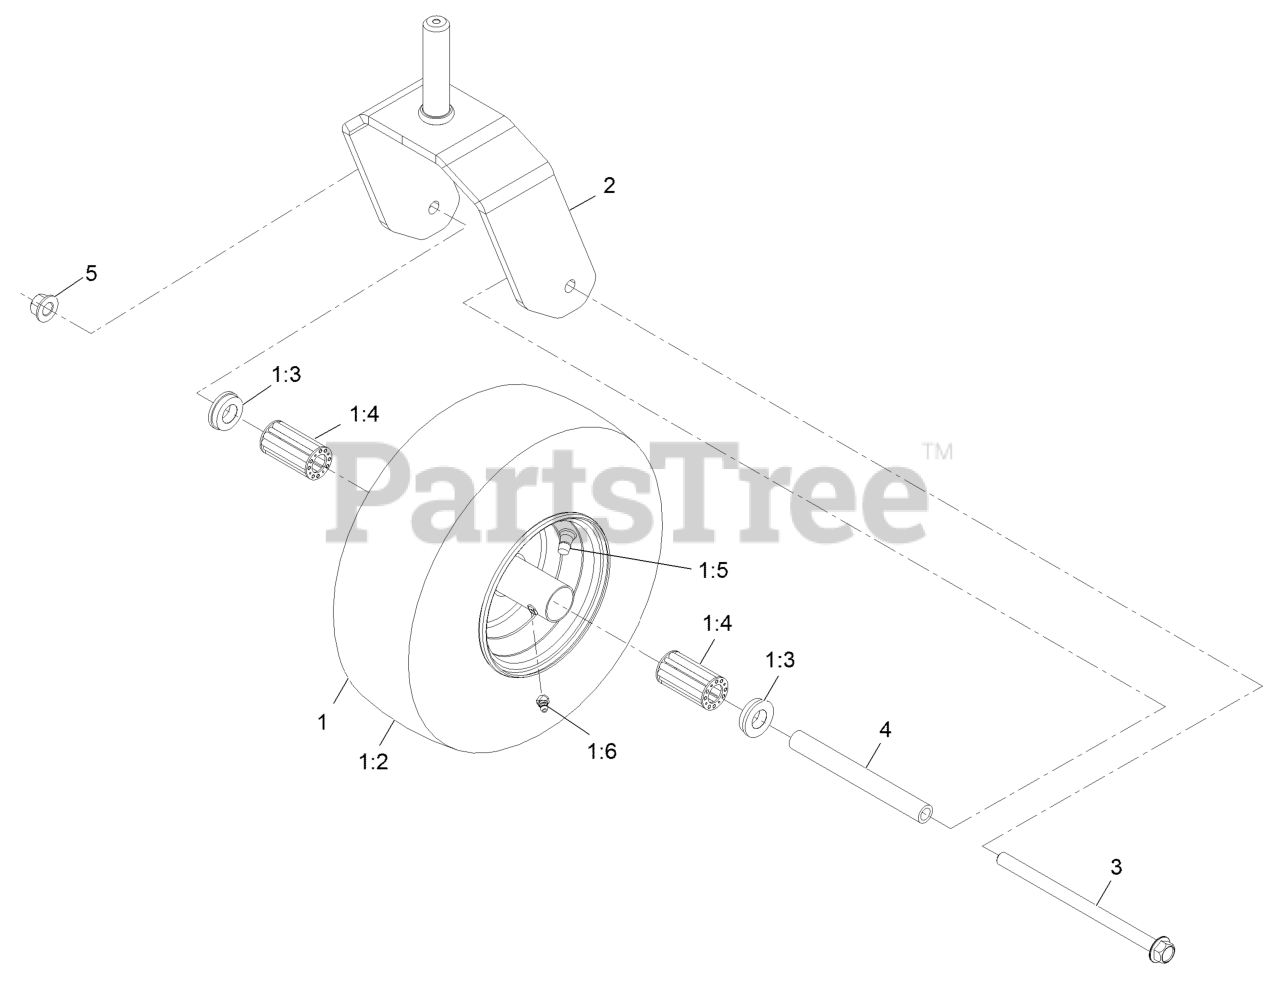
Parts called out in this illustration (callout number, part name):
1	ASM-WHEEL AND TIRE 13X6.5
1:3	BUSHING-FLANGE
1:4	BEARING
1:5	VALVE
1:6	FITTING-ZERK
2	FORK-CASTER
3	SCREW-HHF
4	SPANNER-WHEEL, CASTER
5	Nut-Lock 1/2-13
